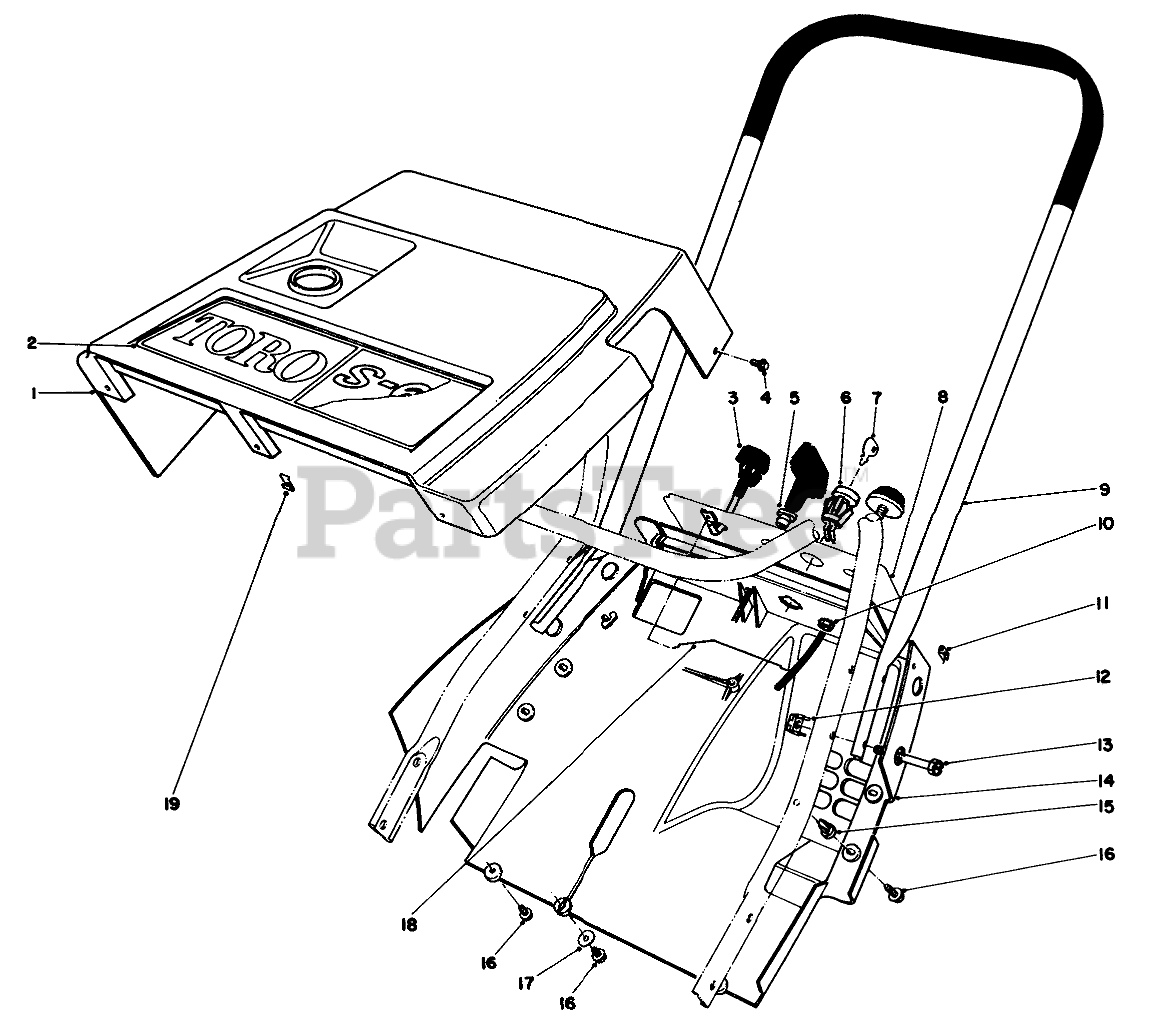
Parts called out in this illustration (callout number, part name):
1	Shroud-Upper
2	TORO DECAL
3	CHOKE CONTROL ASM
4	SCREW-HWHTF
5	GUIDE-ROPE, STARTER
6	SWITCH
7	KEY-IGNITION
8	Decal-Control Panel
9	Handle-Upper
10	NUT-KEPS
12	TINNERMAN NUT
13	SCREW-HEX HD SLOT
14	LOWER SHROUD
15	Nut-Push
16	SCREW-HWHTF
17	WASHER-FLAT
18	CONTROL WIRE
19	NUT "U"
